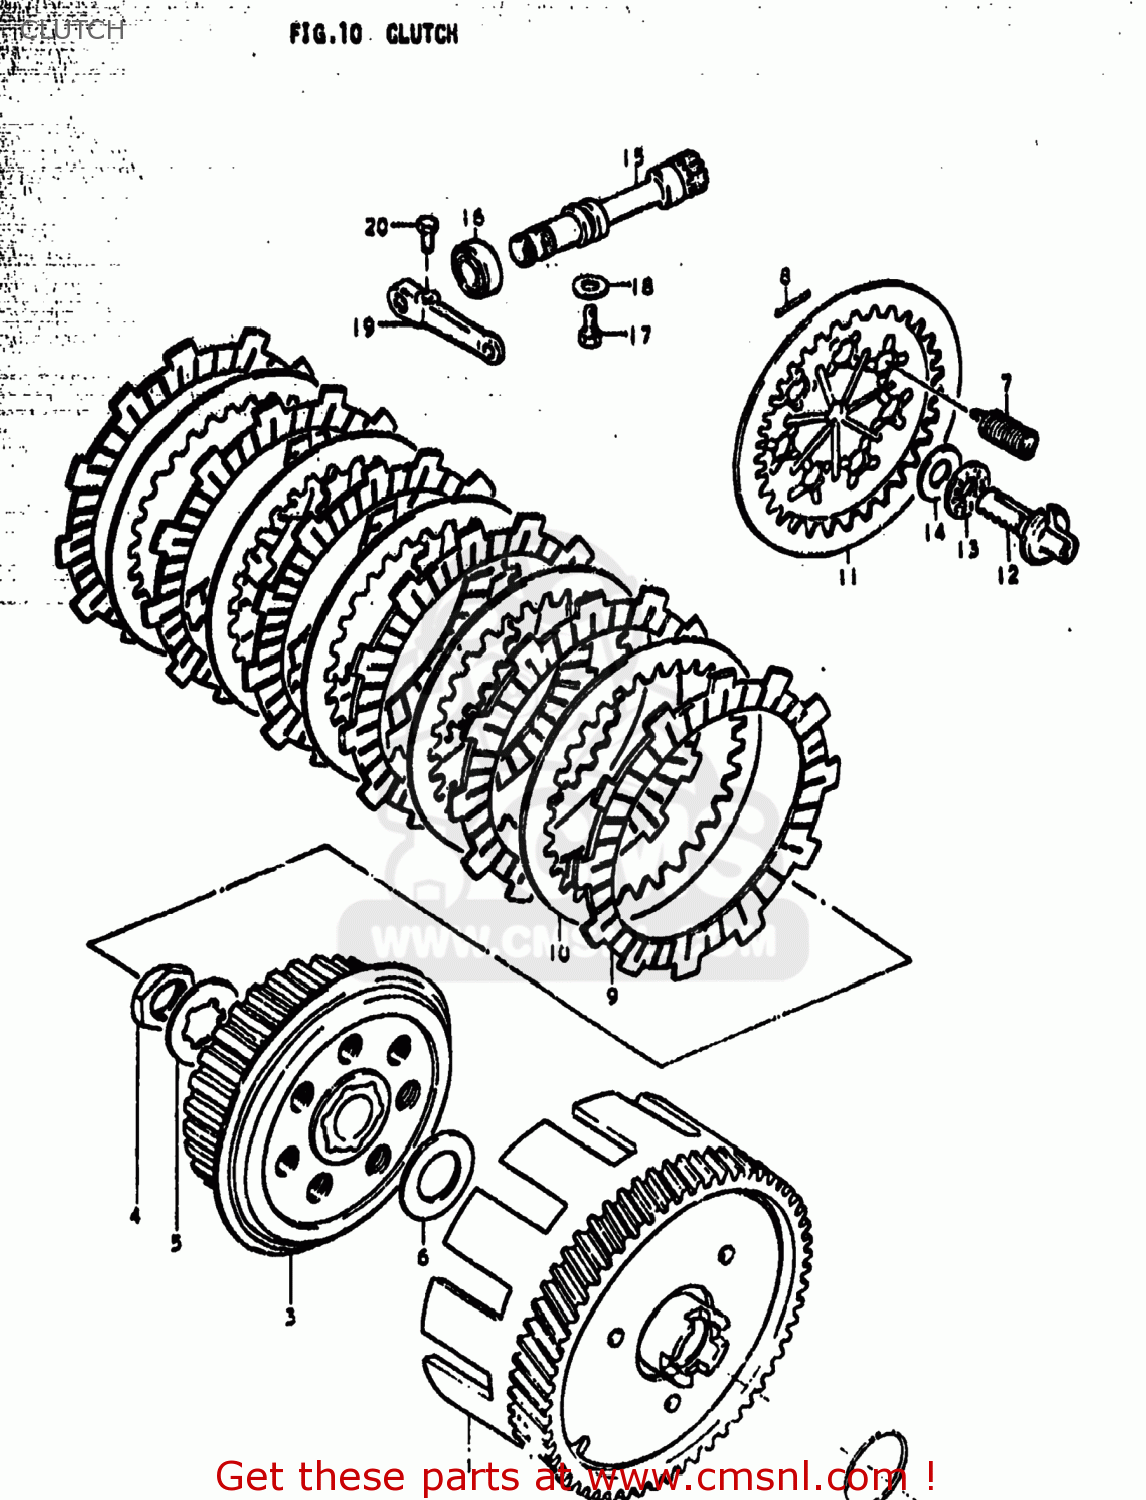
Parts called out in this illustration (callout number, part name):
1	GEAR ASSEMBLY,PRIMARY DRIVE
2	SPRING
3	HUB,CLUTCH SLEEVE
4	NUT
5	WASHER,LOCK
6	WASHER
7	SPRING
8	PIN(2.5X19.8)
9	PLATE,CLUTCH DRIVE
10	PLATE,CLUTCH DRIVEN (NAS)
11	PLATE,CLUTCH PRESSURE
12	RACK,CLUTCH RELEASE
13	BEARING(10X22X2.8)
14	WASHER(10.1X21.4X0.8)
15	PINION,CLUTCH RELEASE
16	OIL SEAL
17	BOLT(6X12)
18	WASHER
19	ARM,CLUTCH RELEASE
20	BOLT
